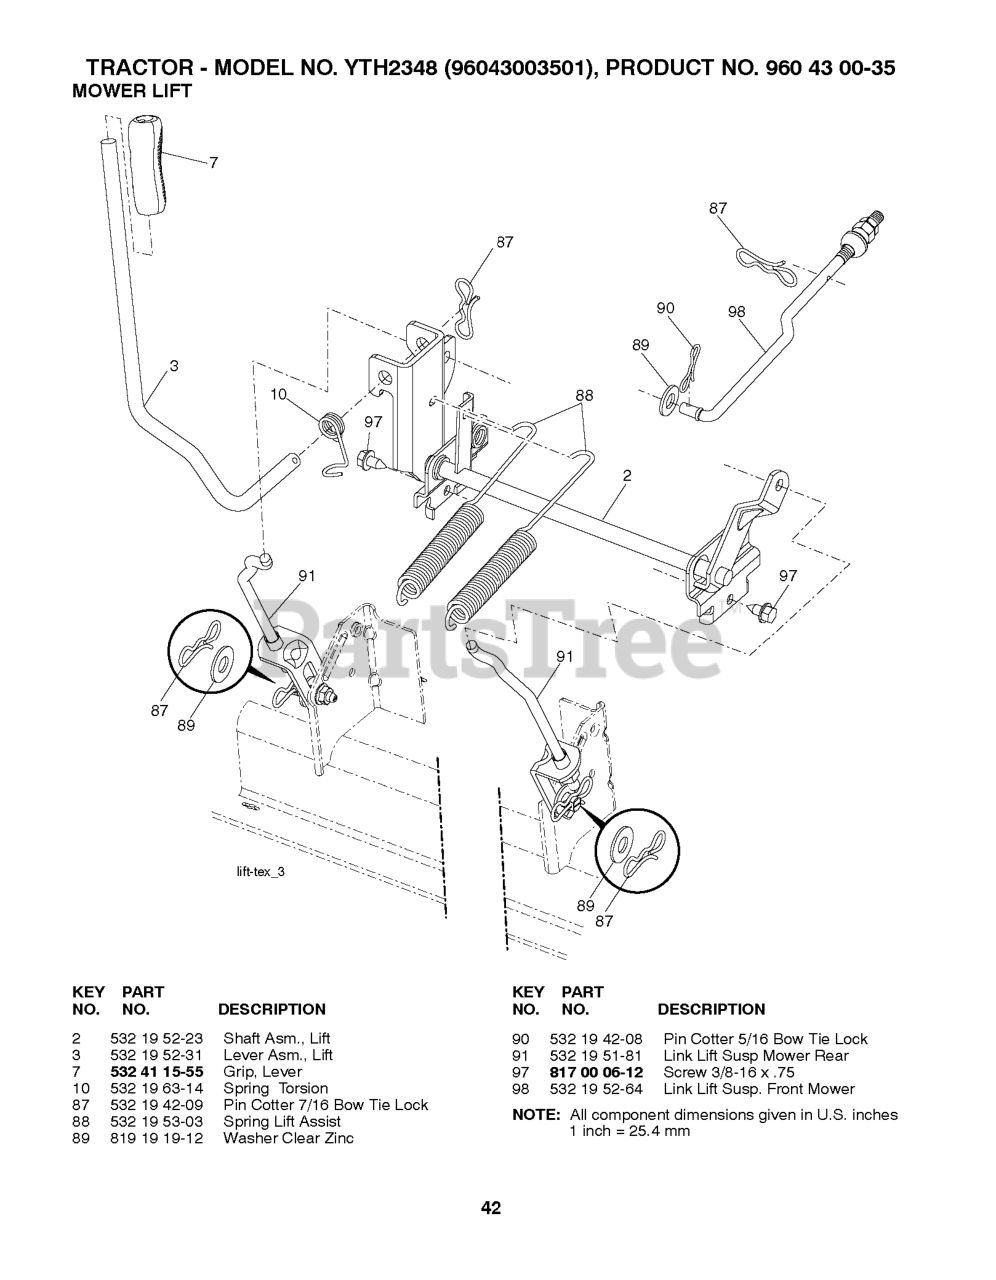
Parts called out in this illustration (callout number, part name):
2	SHAFT.ASM.LIFT.CROSS.H
3	LEVER.LIFT.HANDLE.LT
7	GRIP.HANDLE.LIFT.PVC.BLACK
10	SPRING.TORSION.LIFT.HANDLE
87	PIN.COTTER.7/16.BOW TI.
88	SPRING.LIFT.ASSIST.LT
89	WASHER.CLEAR.ZINC
90	PIN.COTTER.5/16.BOW TI
91	LINK.ASM.LIFT.REAR
97	SCREW, 3/8-16X3/4
98	LINK.ASM.SUSP.FRONT.MWR.10.5
